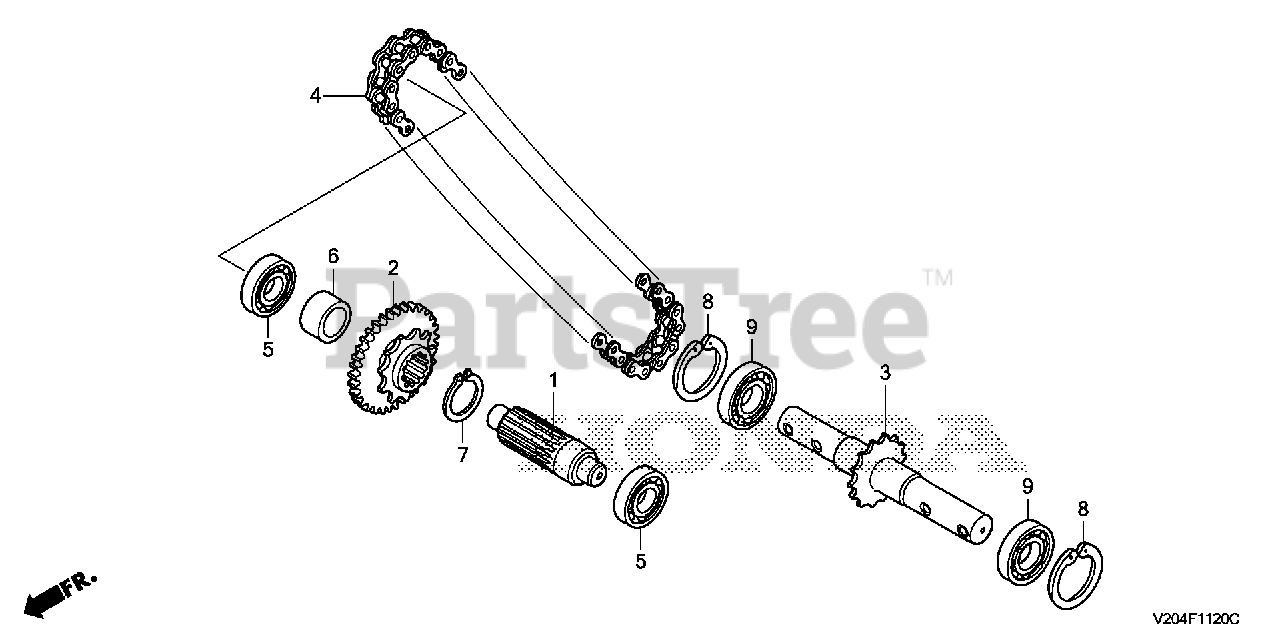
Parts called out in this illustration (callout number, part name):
1	COUNTERSHAFT, P.T.O.
2	GEAR, REDUCTION ROTARY DRIVEN (11T/34T)
3	SHAFT, ROTARY (14T)
4	CHAIN, ROTARY (RK520WS-62L)
5	BEARING, BALL (20X56X16)
6	COLLAR, ROTARY DRIVEN GEAR
7	CIRCLIP (OUTER) (30MM)
8	CIRCLIP (INNER) (62MM)
9	BEARING, RADIAL BALL (6206)
